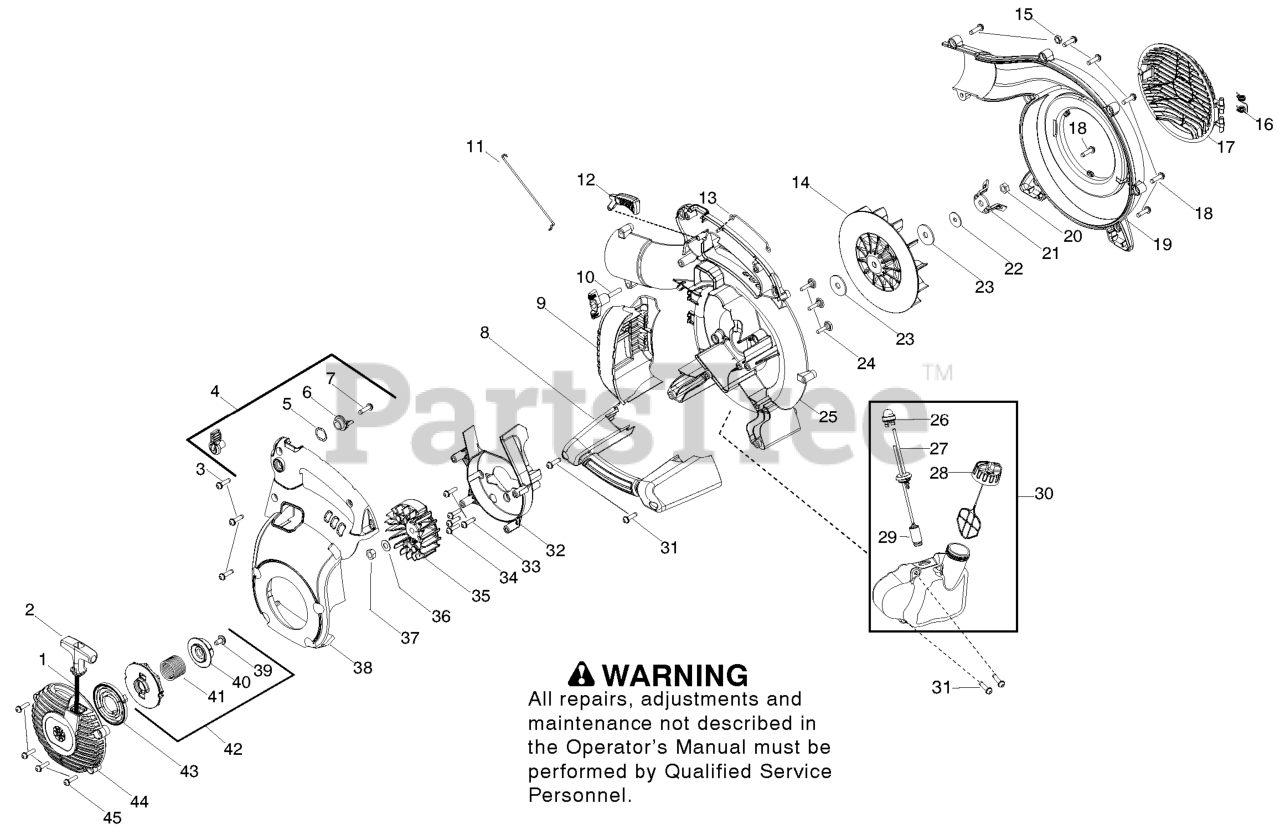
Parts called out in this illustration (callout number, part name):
2	STARTER HANDLE
4	KIT CRUISE CONTROL
5	WAVE WASHER
6	RATCHET CRUISE CONTROL
8	HANDLE ASSIST W/OVER MOLD
9	ASSY, MUFFLER GUARD
10	ASSY, BLOWER KNOB
11	WIRE LINKAGE
12	TRIGGER, THROTTLE
13	WIRE, HANDLE GROUND
14	IMPELLER
16	SPRING, VAC DOOR
17	COVER VAC DOOR
19	OUTER SCROLL ASSY VAC
20	NUT, IMPELLER
21	Blade - Mulch
22	Washer
23	WASHER IMPELLER
24	SCREW FUEL TANK RETAINER
25	SCROLL - INNER
27	KIT FUEL LINE GROMMET
28	ASSY-CAP W/RETAINER
29	FUEL PICK-UP ASSY
30	ASSY, FUEL TANK
32	Scroll - Flywheel
34	SCREW - SHROUD
35	ASSY, FLYWHEEL
36	WASHER FLAT
37	NUT-FLYWHEEL
38	COVER - MOTOR HOUSING
41	SPRING EPS2
42	KIT - STARTER
43	SPRING STARTER
44	HOUSING - STARTER COVER
45	SCREW - SHROUD
